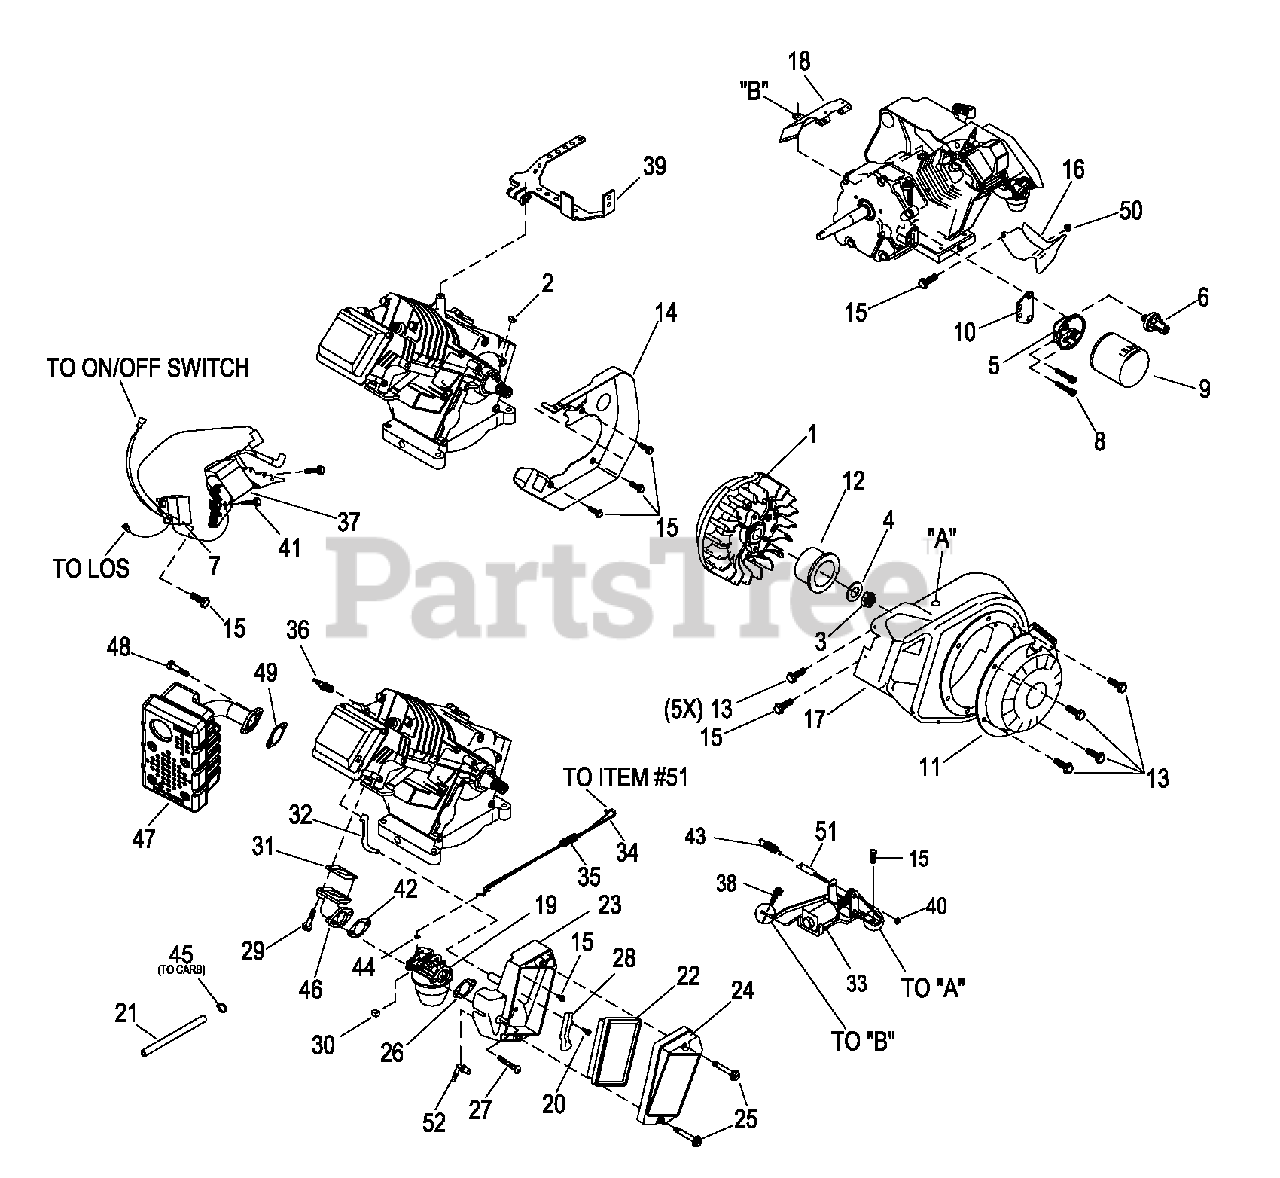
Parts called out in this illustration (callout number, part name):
1	ASSY, FLYWHEEL 29 DEGREE
2	KEY, WOODRUFF 4 X 19 DIAMETER
3	NUT, HEX M16-1.5 G8
4	WASHER, M16 CONICAL
5	ADAPTOR, OIL FILTER GH220
6	OIL PRESSURE SWITCH 5PSI
7	ASSY, LOS MODULE NO LED
8	SCREW, SHC M6-1.0 x 20
9	OIL FILTER BLACK 75mm LONG
10	GASKET, OIL PSI
11	ASSEMBLY, RECOIL STARTER
12	CUP, RECOIL
13	SCREW, HHTT M6-1.0 x 8
14	BACKPLATE, WITH KNOCKOUT GH220
15	SCREW, HHTT M6-1.0 x 10
16	WRAPPER, LOWER GH220
17	BLOWER HOUSING GH220
18	ASSEMBLY, TOP WRAPPER GH220
19	CARB, GH220 WITH CHOKE LEVER
20	SCREW, HHTT M5 - 0.8 X 12 BP
21	HOSE, 1/4" SAE30R11 GREENBAR 14"
22	ELEMENT, AIR CLEANER
23	BASE, AIR CLEANER W/EVAP
24	COVER, AIR CLEANER
25	SCREW, HHSFC M6-1.0 x 31
26	GASKET, CARB / MANIFOLD W/O ADHESIVE
27	BOLT, CARBURETOR MOUNTING
28	COVER, BREATHER CANAL
29	SCREW, HHFC M6-1.0 x 30
30	KNOB, CHOKE LEVER
31	GASKET, MANIFOLD / HEAD
32	HOSE, BREATHER GH220
33	IDLE CONTROL ASSY, GOV SF
34	GOVERNOR ROD
35	ANTI-LASH SPRING
36	SPARK PLUG GAP: 0.030"
37	ASSY, IGNITION COIL ADVANCED NO DIODE
38	SCREW, HHTT M8-1.2 x 16
39	GOVERNOR LEVER
40	NUT, HEX LOCK M5-0.5 NYLON INSERT
41	SCREW, HHTT M6-1.0 x 25 ZINC
42	GASKET, CARBURETOR / AIRBOX
43	SPRING, GOVERNOR
44	WASHER, NYLON 0.12ID x 0.28OD
45	CLAMP, HOSE #5.5
46	INTAKE MANIFOLD
47	MUFFLER, GH220 SIDE-OUT
48	SCREW, SHC M8-1.25 x 20 SEMS
49	GASKET, EXHAUST
50	GROMMET, 9/16" x 1/16" X 7/16"
51	BOLT, GOV ADJ M5
52	BARBED ELBOW 1/8 NPT X 3/8 NY
